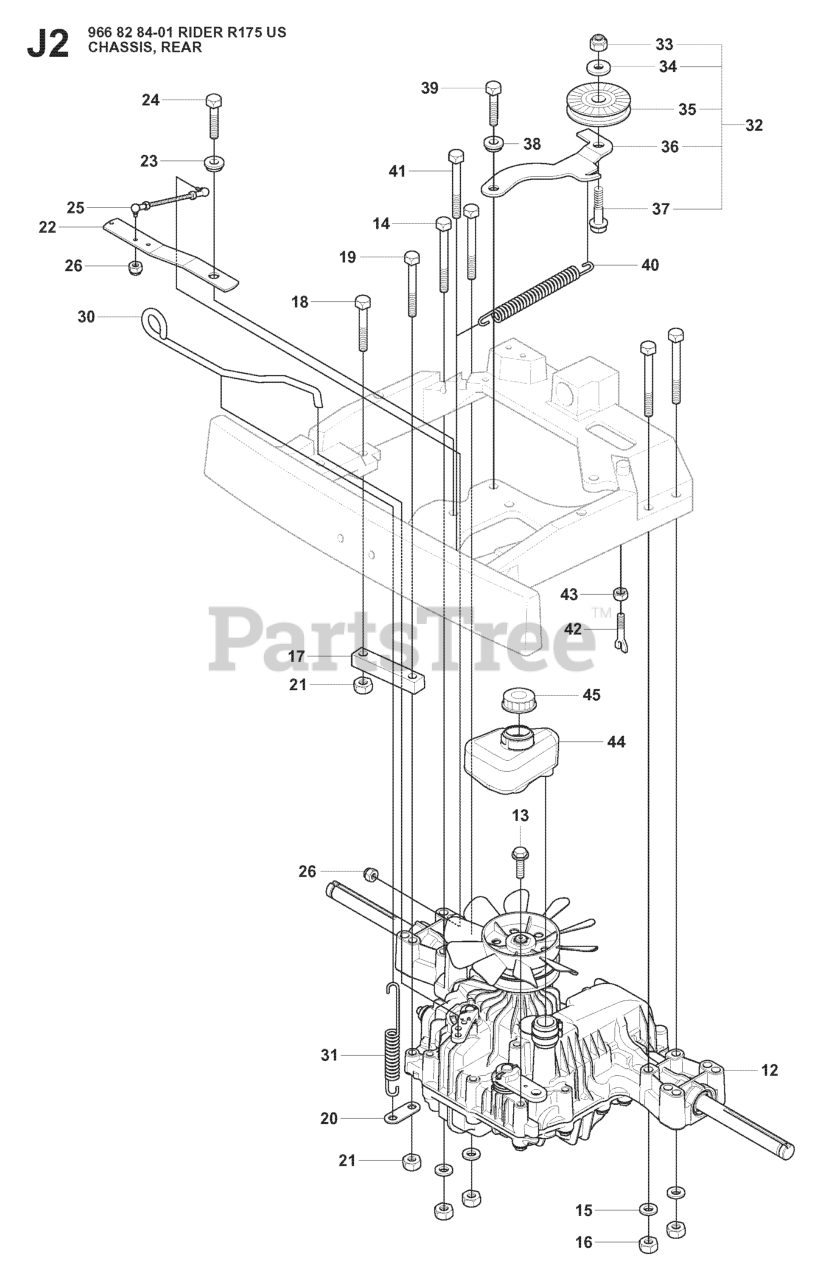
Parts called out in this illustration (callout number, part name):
12	HYDROSTAT 7A646024070
15	WASHER BRB 8.4X17
16	NUT
21	NUT
23	WASHER
24	SCREW 8X20
26	LOCKNUT M5
33	TENSIONER
35	SCREW
37	LOCKNUT M8
38	WASHER
39	SCREW 8X20
43	NUT
45	TANK CAP
